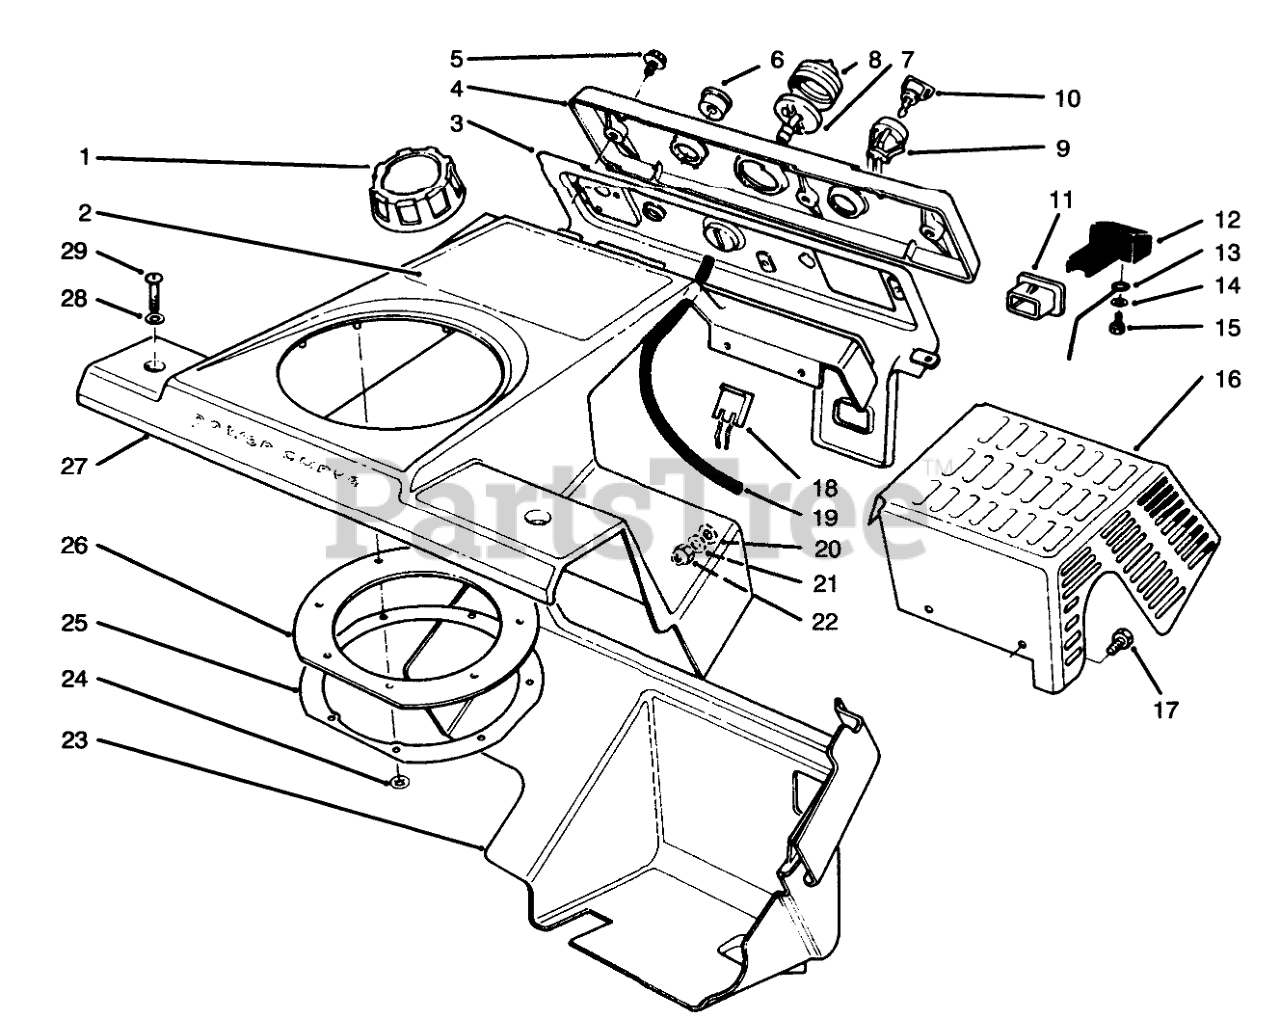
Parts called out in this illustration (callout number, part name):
1	CAP-FUEL ASM
2	DECAL - CCR 2000
3	Control Panel Assembly (Incl. Ref. #6-8 & 11)
4	CONTROL NAMEPLATE
5	SCREW-HWH
6	GUIDE-ROPE, STARTER
7	BODY-PRIMER
8	BULB-PRIMER
9	SWITCH
10	KEY-IGNITION
11	FITTING
12	CONTROL-CHOKE
13	Unkage-Choke
14	WASHER-PLAIN
15	SCREW-PPH
16	Wa-Shield
17	SCREW-SHH
18	CONNECTOR-BODY
19	PRIMER HOSE
20	WASHER
21	WASHER-FLAT
22	NUT-LOCK, NI
23	LOWER SHROUD
24	PALNUT
25	Retainer-Chute Seal
26	SEAL-CHUTE
27	Upper Shroud Assembly (Incl. Ref. #2 & 24-26)
28	WASHER-FLAT
29	SCREW-PPH
